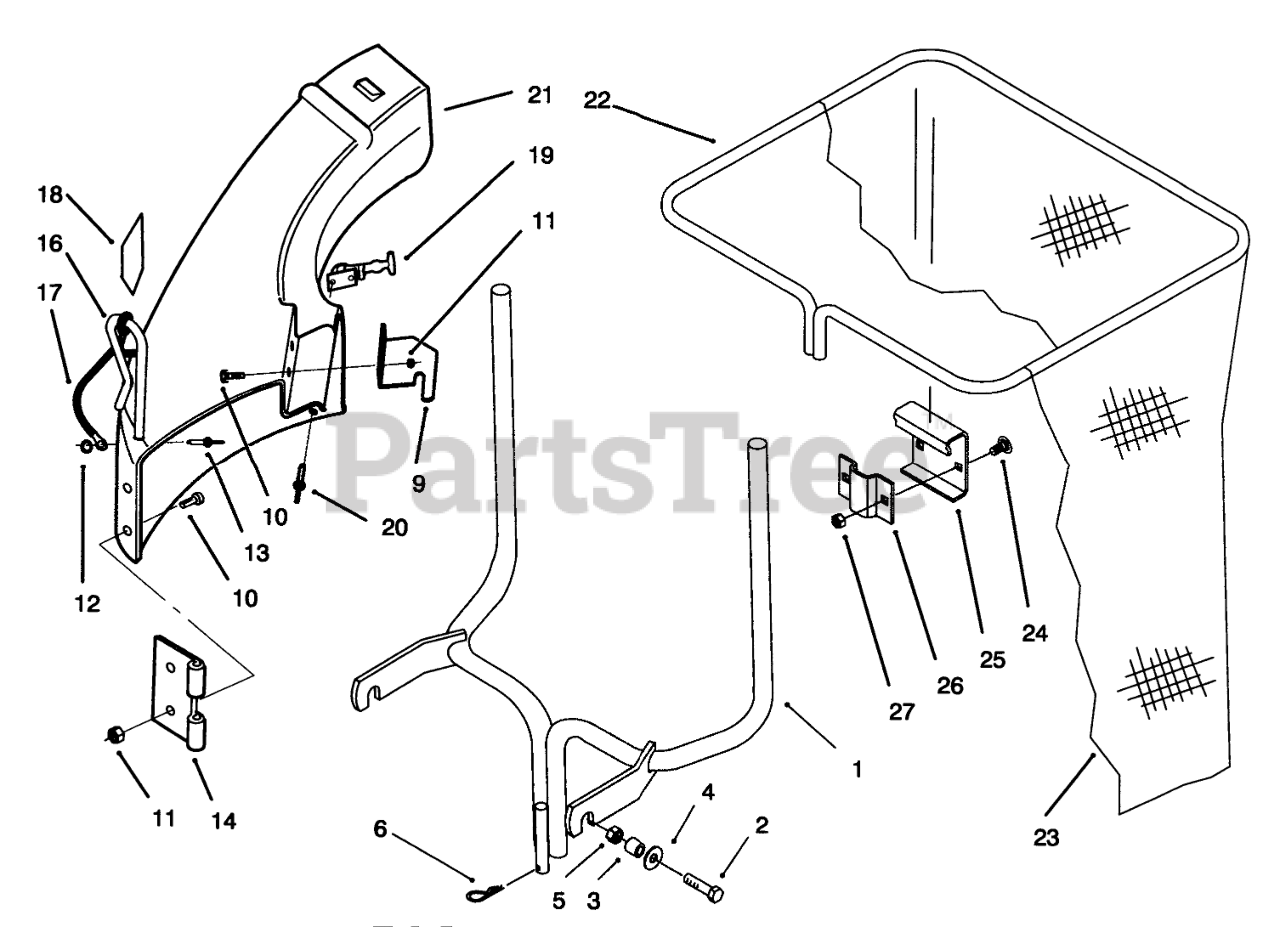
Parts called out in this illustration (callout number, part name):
1	Bracket-Quick Attach
2	SCREW-HH
3	SPACER
4	WASHER
5	NUT-LOCK, NI
6	Hairpin
9	LATCH-BAGGER ELBOW
10	Bolt
11	NUT-LOCK, NI
12	Washer
13	RIVET-POP
14	BRACKET-MOUNTING, CHUTE
16	PIN-LOCKING, CHUTE
17	LANYARD
18	DECAL-DANGER
19	Latch-38"
20	RIVET-POP
21	Chute Assembly (Incl. Ref. #9-15 & 17-20)
22	Bag Frame
23	BAG-DEPTH
24	BOLT-CARR
25	Bag Hanger
26	Clamp
27	NUT-LOCK, NI
